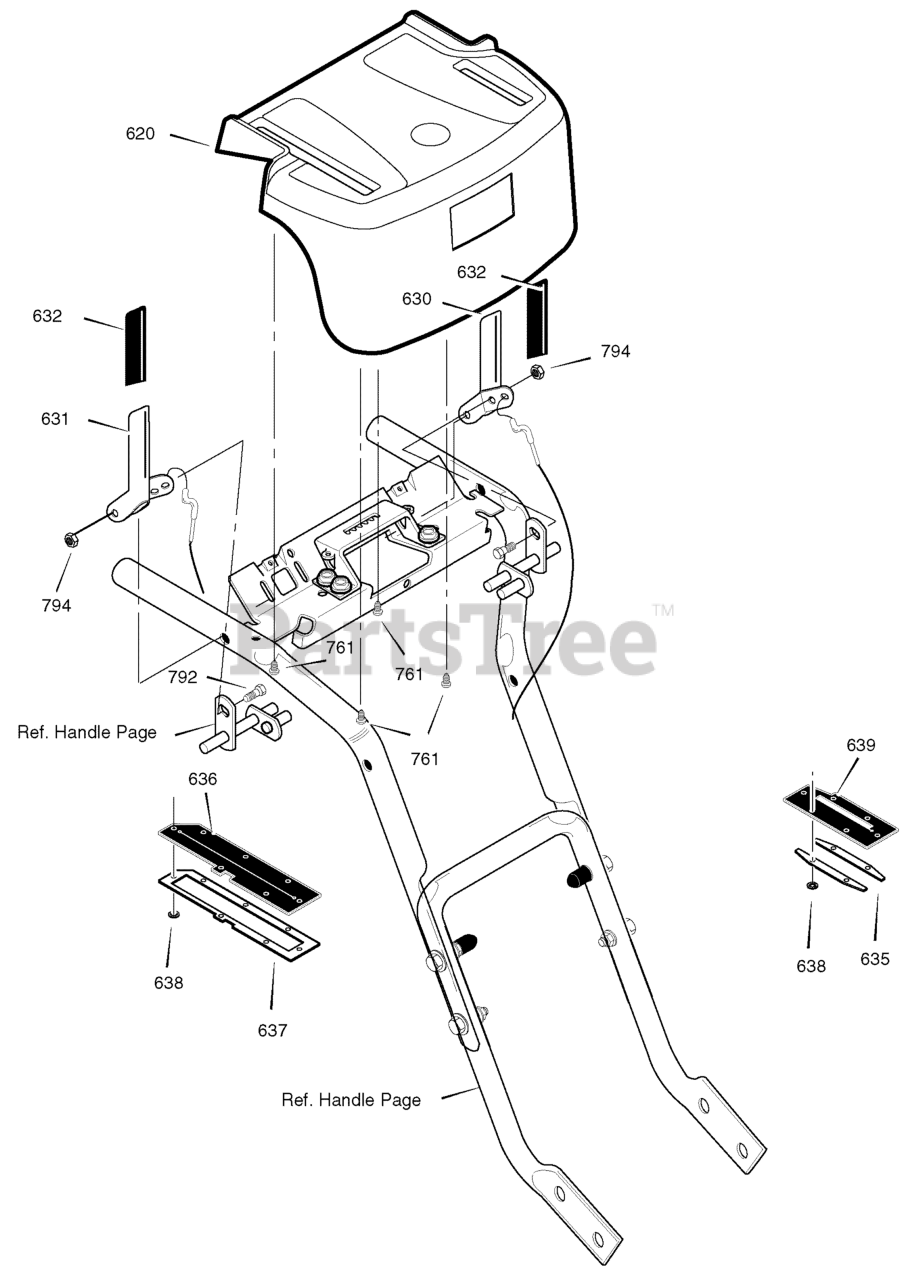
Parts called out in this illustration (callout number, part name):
620	PANEL, CONTROL W/LIGHT
630	CLUTCH HANDLE LH
631	CLUTCH HANDLE RH
632	GRIP, CLUTCH LEVER
635	FRAME, COVER
636	COVER, SPEED LEVER
637	FRAME, SPEED COVER
638	NUT, PUSH
639	COVER, CHUTE LEVER
792	BOLT, 1/4-20 X 0.50
794	NUT, 1/4-20
